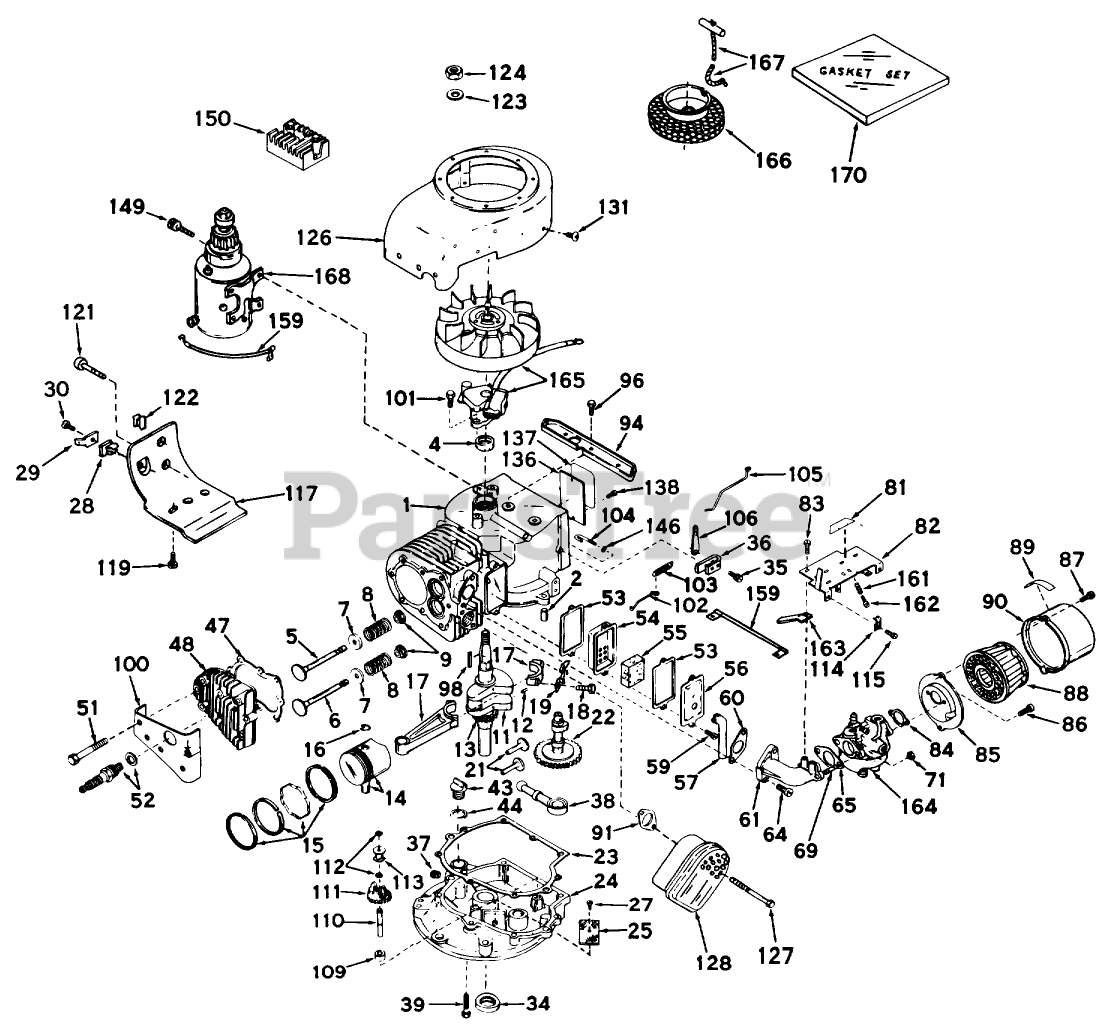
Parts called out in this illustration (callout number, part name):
1	Cylinder Assy. (Incl Nos. 2 4)
2	Pin-Dowel
4	Oil Seal
5	Valve, Intake (Standard)(Incl. No. 9)
5	Valve, Intake (1/32" oversize)(Incl. No. 9)
6	Valve, Exhaust (Standard)(Incl. No. 9)
6	Valve, Exhaust (1/32" oversize)(Incl. No. 9)
7	Cap-Spring, Valve
8	Spring-Valve
9	Keeper-Spring, Valve
11	Crankshaft Assy. (Incl. Nos. 12 13) (Model V70-125130)
12	Pin, Groove
13	Gear-Crankshaft
14	Piston Pin Assy. (Incl. 2 of No. 16)(Standard)
14	Piston Pin Assy. (Incl. 2 of No. 16)(.010 oversize)
14	Piston Pin Assy. (Incl. 2 of No. 16)(.020 oversize)
15	ORing
15	Ring Set (.010" OS)
15	Ring Set (.020" OS)
17	Rod Assy., Connecting (Incl. Nos. 18 19)
18	Screw, Hex Hd.
19	Plate, Lock
21	Lifter Valve
22	Screw
23	Gasket-Cover, Cylinder
24	Flange Assy., Mounting (Incl. Nos. 25, 27, 29, 34, 45 110)
25	Screen-Oil Filter
27	Screw
28	Grommet
29	Terminal
30	Screw
34	Seal-Oil
35	Screw
36	Clamp-Lever, Governor
37	Plug-Drain, Oil (SQH 1/4-18)
38	Pump, Oil
39	Screw (1/4-20 x 1-1/4)
43	Plug-Fill, Oil
44	Gasket
47	Gasket-Cylinder Head
48	Head, Cylinder
51	Screw
52	SPARK PLUG
53	Gasket-Breather
54	Body-Breather
55	Element-Breather
56	Cover-Valve
57	Tube-Breather
59	Screw
60	Gasket-Intake
61	Pipe-Intake
64	Screw (T-30, 5/16-18x1-3/32)
65	Gasket
69	Stud
71	Nut and Lock Washer (1/4-28)
81	Decal, Speed control
82	Control Assy., Speed
83	Screw (10-24 x 9/16)
84	Gasket
85	Bracket
86	Screw (10-32 x 1/2)
87	Screw
88	Element
89	Decal
90	Body
91	Gasket Exhaust
94	Bracket, Blower Housing (Incl. Nos. 131)
96	Screw (1/4-20x19/32)
98	Key-Flywheel
100	Cover, Cylinder head
101	Screw, Hex Hd. Cap, Sems
102	Link Governor Spring
103	Spring Governor
104	Rod, Governor (Incl. Nos. 146)
105	Link Governor
106	Lever-Governor
109	Spacer
110	Shaft, Governor
111	Governor Gear ASM
112	Ring-Retaining
113	Spool-Governor
114	Conduit
115	Screw (10-32 x 3/8)
117	Emnsion, Blower Housing
119	Screw
121	Screw
122	51004 GIL ROTARY TI
123	Washer
126	Housing, Blower
127	Screw
128	Muffler
131	Screw, Hex Hd.
136	IDENTIFICATION PLATE
137	480B GIL SNWTHWR O/
138	Stud
146	Washer-Flat
149	Screw
150	Regulator, Rectifier
159	Wire, Ground
161	Spring-Compression
162	Screw
163	Clip
164	Carburetor
165	Magneto, Alternator
166	Hub Screen, Rope Starter
167	Rope Assy., Starter
168	Motor, Starter
170	Gasket Set
